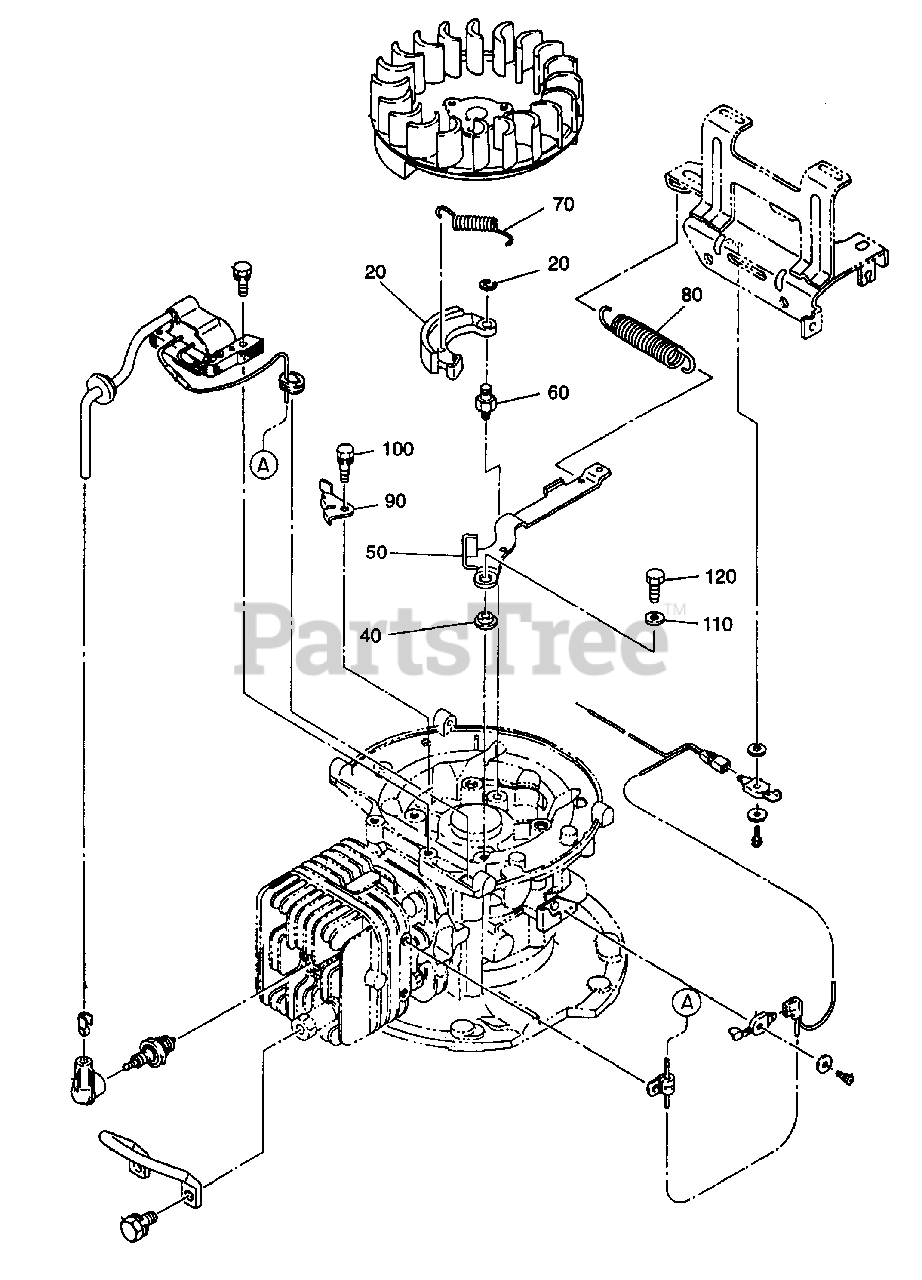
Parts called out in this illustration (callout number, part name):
30	BRAKE SHOE CP
50	CONTROL LEVER
60	PIVOT BOLT CP
70	RETURN SPRING
80	BRAKE SPRING
90	BRACKET, BRAKE
100	BOLT & WASHER ASSY
100	BOLT AND WASHER ASSY
